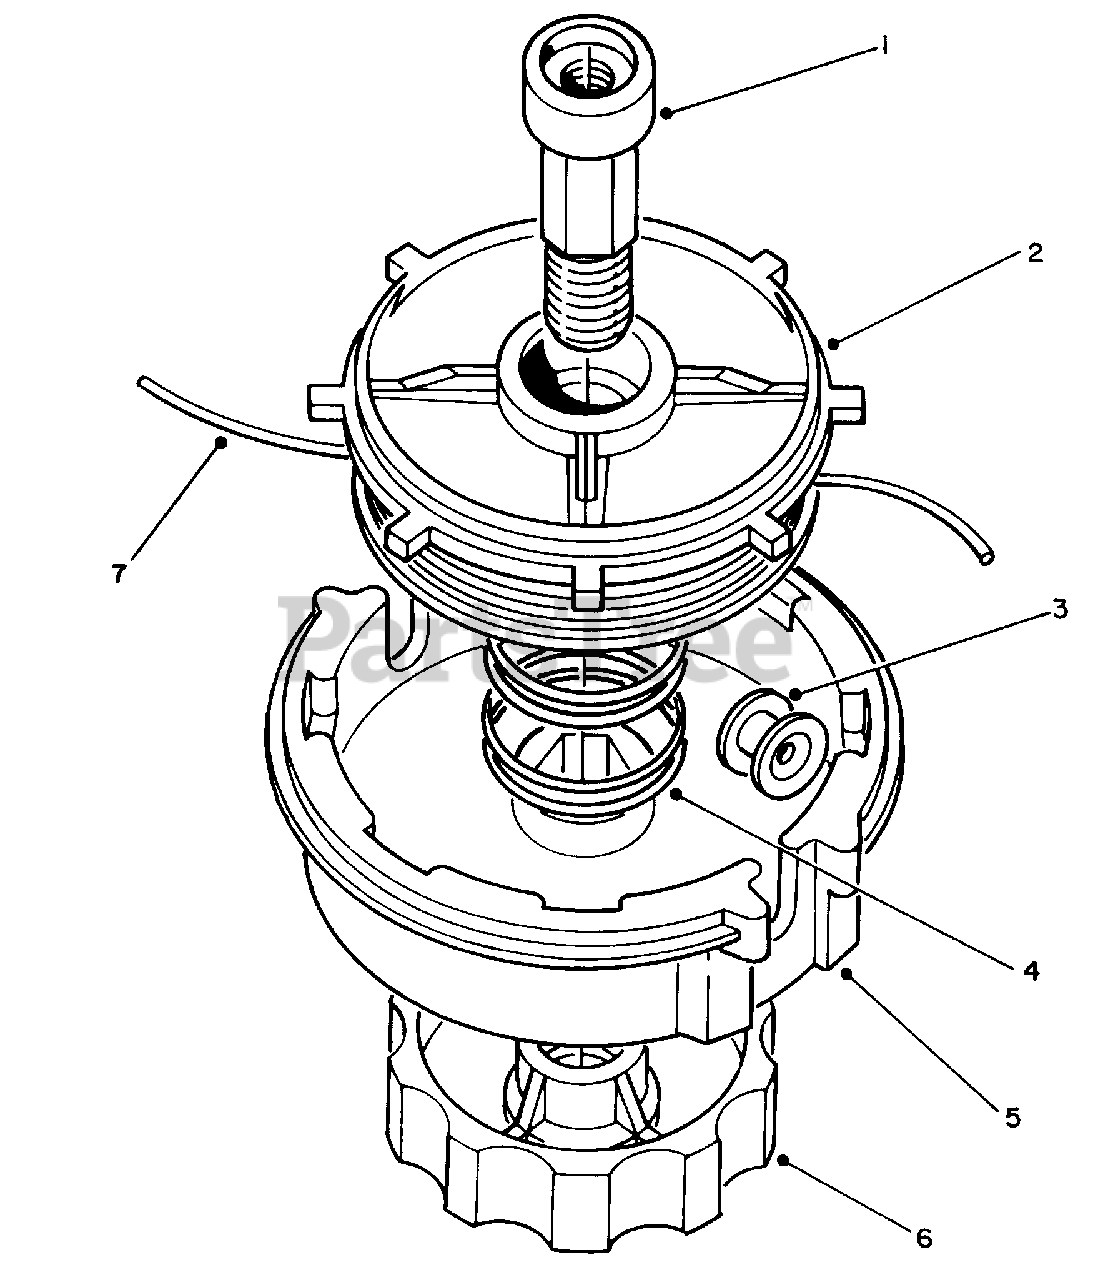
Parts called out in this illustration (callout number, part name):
2	Spool-Inner
5	Housing-Spool
6	Knob-L.H.
7	.105 Line
